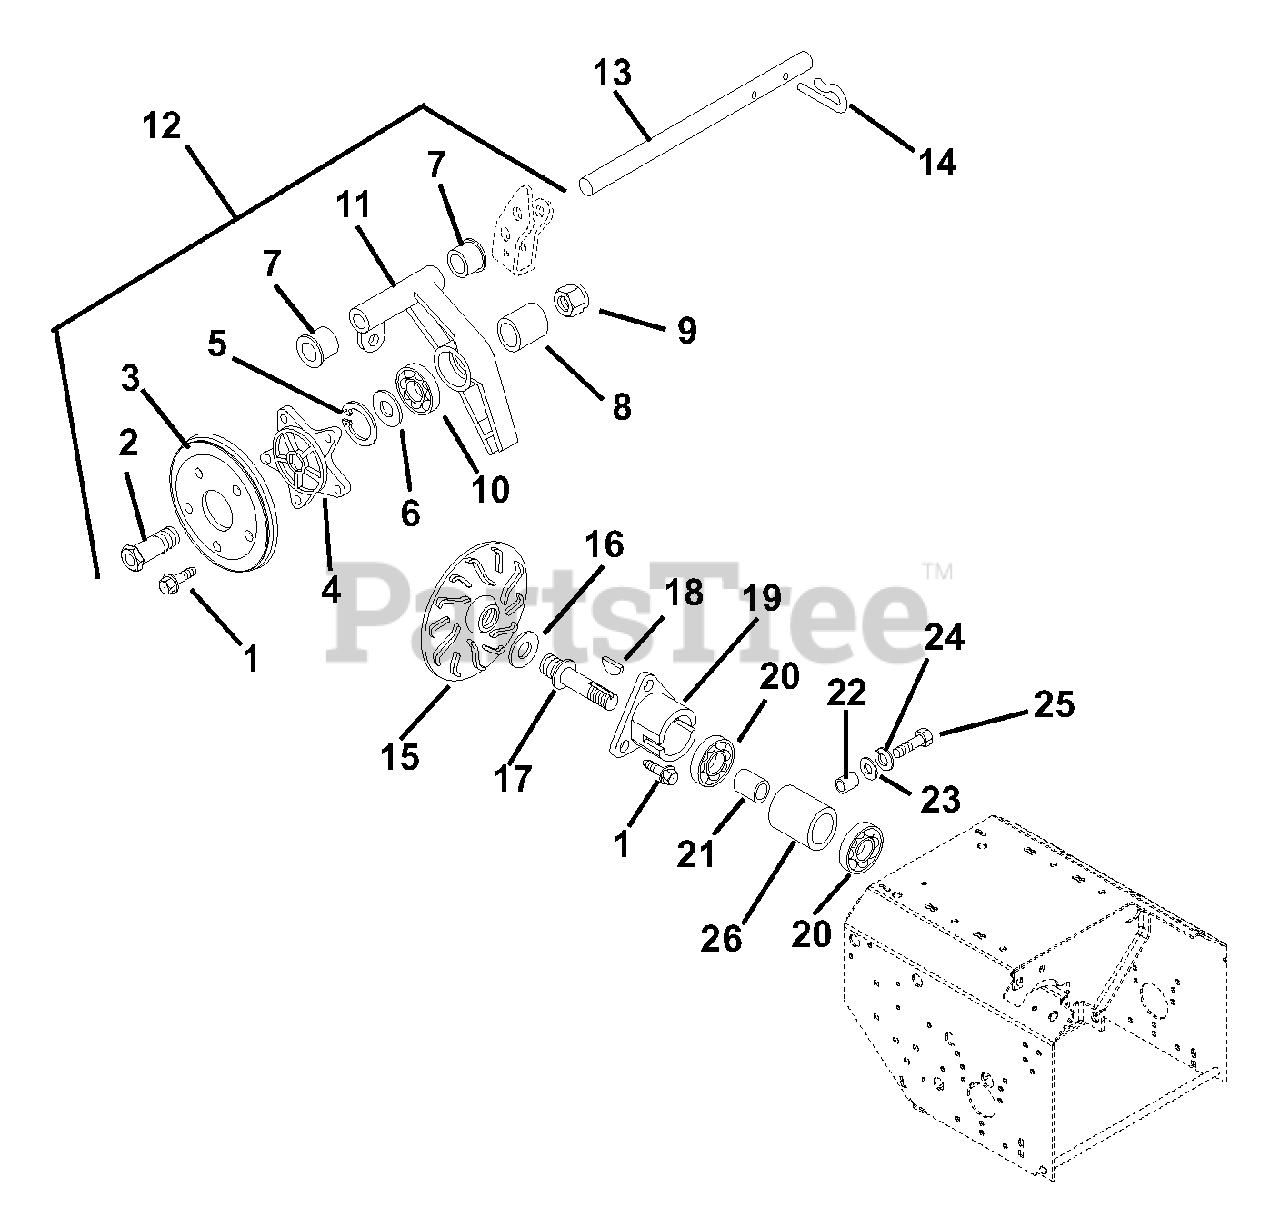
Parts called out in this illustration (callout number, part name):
1	@SCR-TAP .31-18X.50 HWH TR YWZ
2	SPINDLE HUB
3	FRICTION, DISC
4	DISC HUB
5	RG-RTNG-INT 1.750X.062
6	WSHR-FL-STL .880X1.250X.062YWZ
7	BSHG-FLG .625X.750X.500X.875BR
8	BSHG-SLV .882X1.250X.531
9	NUT-LK-NYL .875-14 YWZC
10	BRG-BALL .876 X 1.750 X .50
11	CARRIER
12	FRICTION WHEEL ASSEMBLY
13	SHAFT, CARRIER
14	PIN, SPRING CLIP
15	DRIVE PLATE
16	DRIVE DISC SPACER 1.3X.76X.19
17	SPINDLE
18	KEY-FTHR .125X.50X.194 HP 404
19	HOUSING MOUNT
20	BRG-BALL .625X1.375X.43
21	BEARING SPACER
23	@WSHR-FL-STL.344X.688X.065YWZC
24	@WSHR-LK .31X.078 REG YWZC
25	@BLT-HEX .31-18X1.00 GR5 YWZC
26	SPINDLE HOUSING
